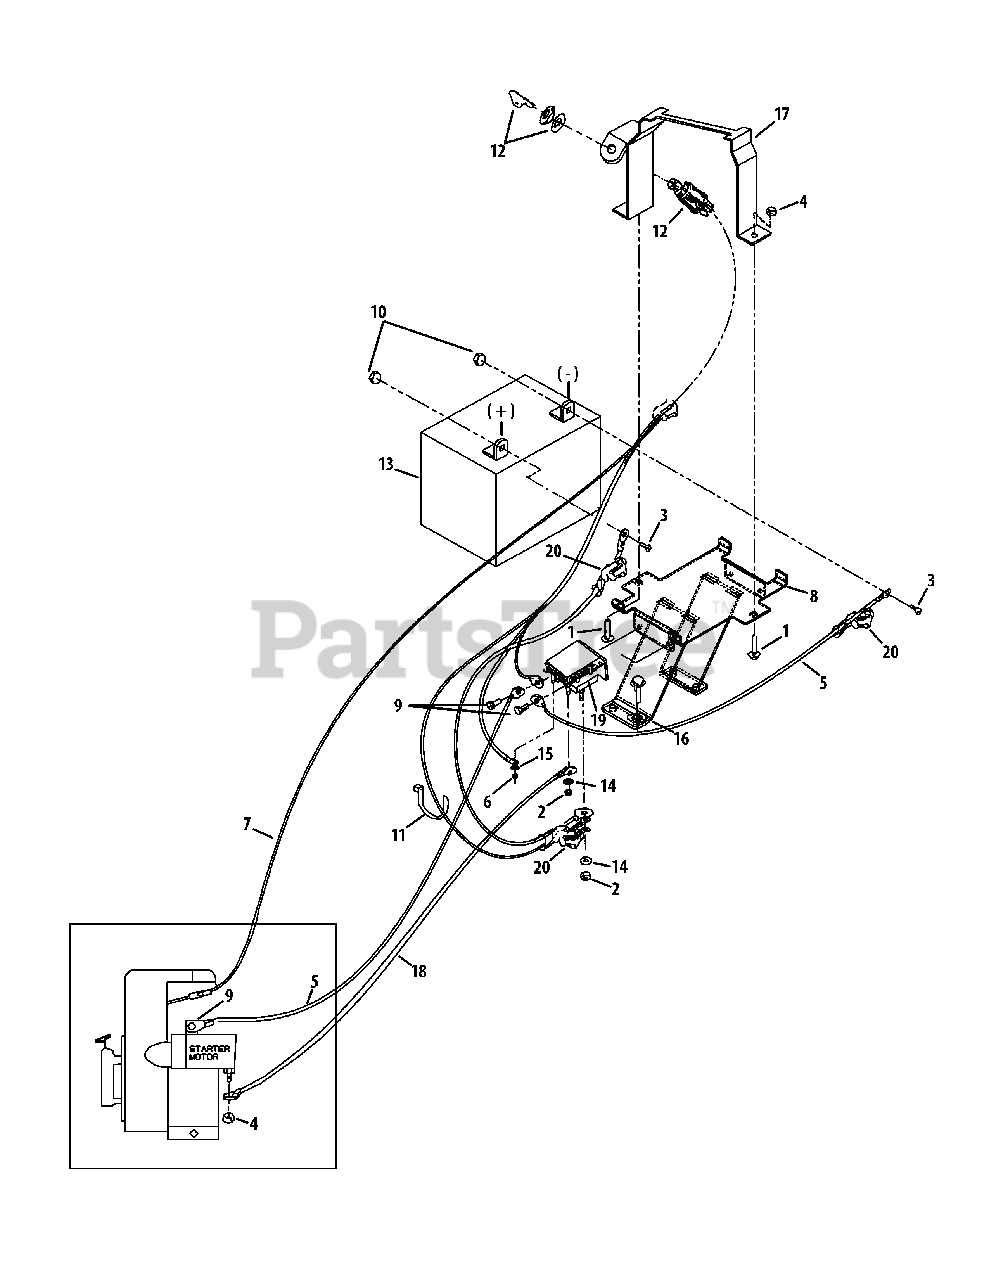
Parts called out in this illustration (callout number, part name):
1	Carriage Screw 1/4-20 x 125
2	Hex Nut 5/16-24
3	Flange Screw 1/4-20 x 625
4	Hex Locknut 1/4-20
5	Cable (Ground Wire)
6	Hexlock Washer Nut, 10-32
7	Electric Start Harness
8	Battery Bracket Assembly
9	Self-tapping Screw 1/4-20 x 5
10	Hex Nut 1/4-20
11	Cable Tie
12	Ignition Switch
13	Battery 270 CCA
14	Lock Washer 5/16
15	Lock Washer #10
16	External Lock Washer 5/16
17	Keyswitch Clamp
18	Cable (Solenoid to Starter Motor)
19	Solenoid (Incl Nuts and Washers for Cables and Wires)
20	Insulating Boot
